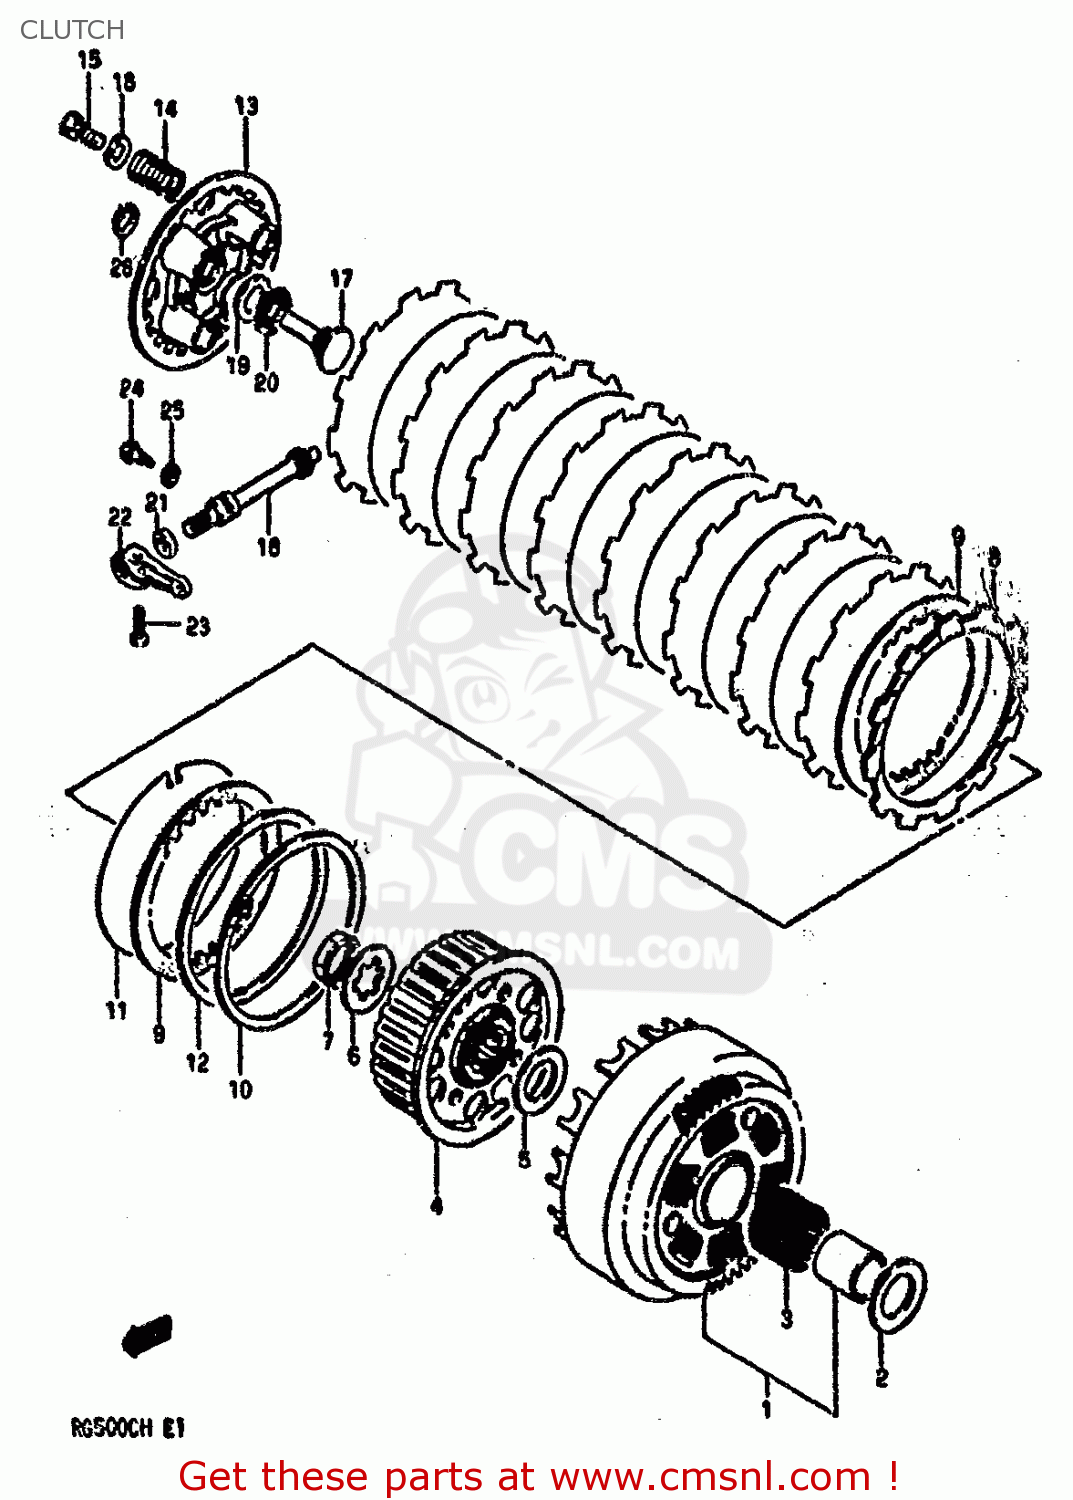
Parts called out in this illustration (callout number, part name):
1	GEAR ASSY,PRI DRIVEN
2	WASHER(22X42X2.5)
3	BEARING
4	HUB,CLUTCH SLEEVE
5	WASHER(22X40X1.5)
6	WASHER,LOCK
7	NUT
8	PLATE,CLUTCH (MCA)
9	PLATE,CLUTCH D
10	SEAT,WAVE WASHER
11	RING,WAVE WASHER STOPPER
12	WAVE WASHER
13	DISC,CLUTCH PRESSURE
14	SPRING
15	BOLT
16	WASHER
17	RACK,CLUTCH RELEASE
18	PINION,CLUTCH RELEASE
19	WASHER
20	BEARING(15X28X2)
21	OIL SEAL
22	ARM,RELEASE
23	BOLT
24	BOLT(6X12)
25	WASHER
26	RING,SNAP
